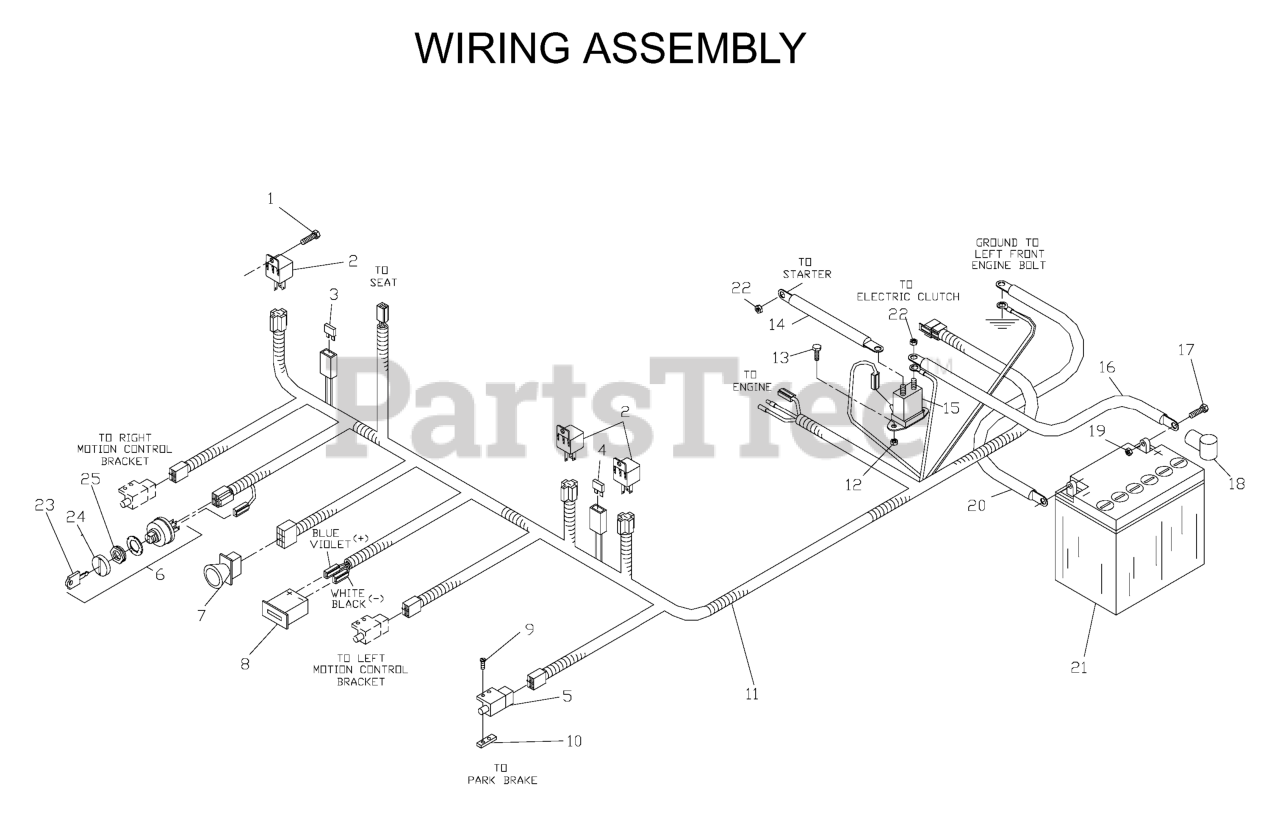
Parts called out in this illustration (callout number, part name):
1	SCREW #10 X 1/2 SELF TAPPING
3	FUSE, 7.5 AMP 32 VOLT ATO
4	FUSE, 20 AMP 32 VOLT ATO
5	SWITCH, INTERLOCK
6	IGNITION SWITCH KIT
7	RP.SWITCH, BLADE
8	HOUR METER
9	SCREW #10-24 X 5/8
10	TAPPED PLATE
11	WIRING HARNESS-KAW MINI
12	NUT 1/4C CENTERLOCK
13	HCS 1/4C X 5/8
14	CABLE POSITIVE
16	CABLE POSITIVE, LONG
17	HCS 5/16C X 3/4
19	NUT 5/16C CENTERLOCK
20	CABLE-NEGATIVE
21	BATTERY WET NOT SELLABLE
22	NUT.1/4-20.HEX.NYLOC.ZD
23	KEY-PADDED
24	DNO IGNITION NUT
25	CAP IGNITION NUT
